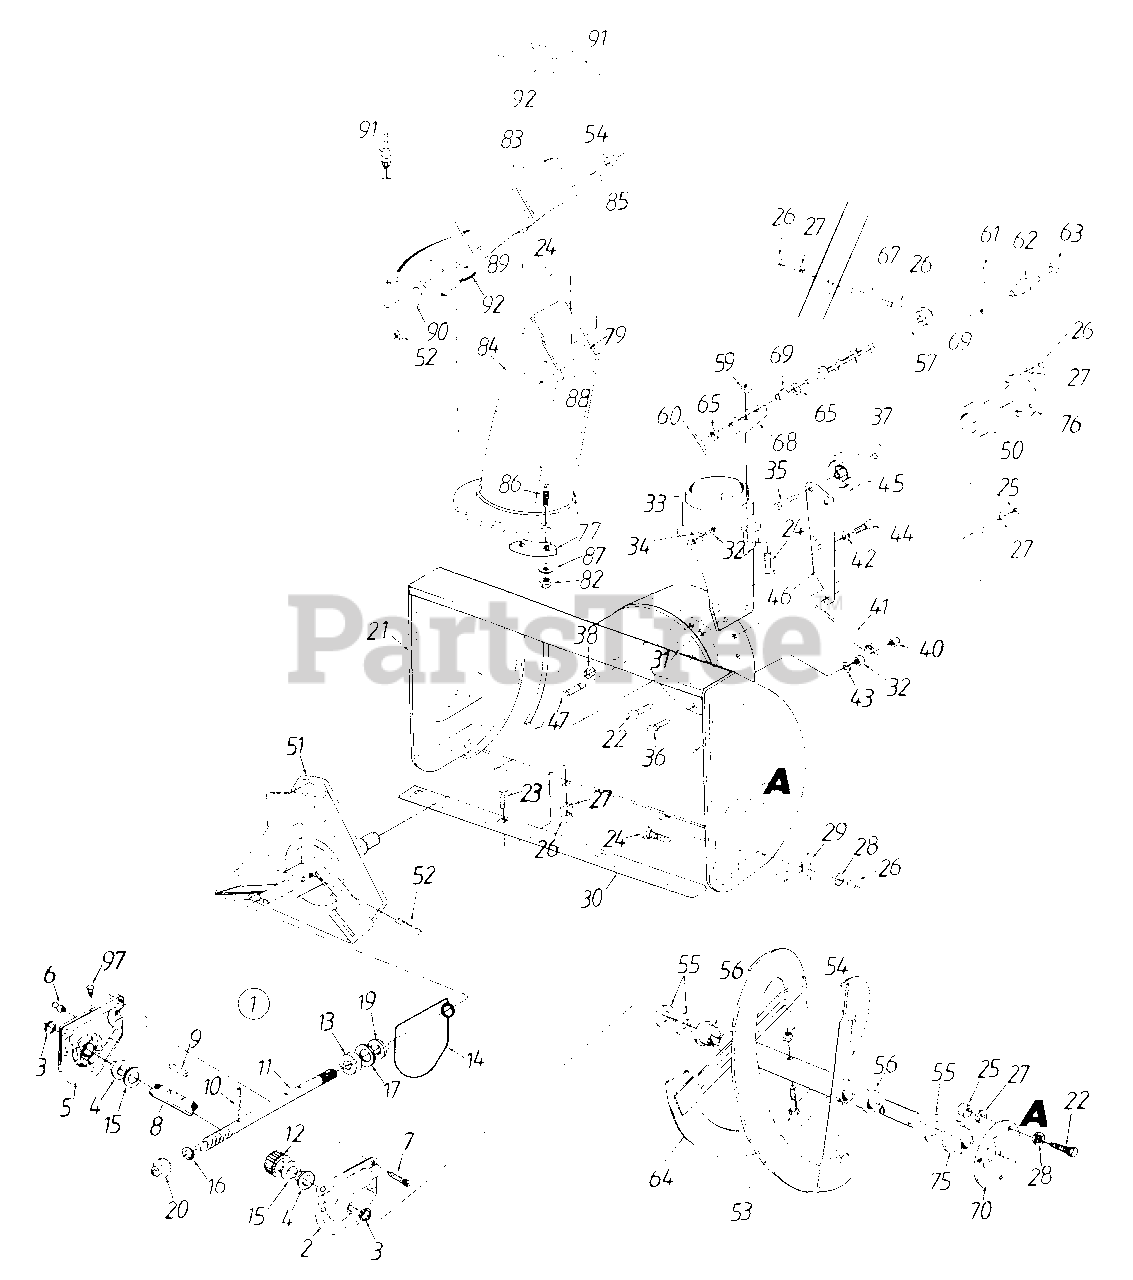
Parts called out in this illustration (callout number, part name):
1	Worm Drive Ass'y. Comp.
2	Reducer Housing - L.H.
3	Oil Seal
4	Flange Bearing .75" I.D.
5	Reducer Housing - R.H.
6	Grease Fltting
7	Hex TT-Tap Scr. 1/4-20 x .75" Lg.
8	24" Auger Shaft
9	#61 Hi-Pro Key 3/16" x 5/8" Dia.
10	Spiral Pin 1.25" Lg.
11	Impeller Shaft
12	Worm Gear
13	Thrust Collar
14	Oil Seal
15	Fl-Wash .76" I.D. x 1.5" O.D.
16	Fl-Wash .5" I.D. x 1" O.D.
17	Fl-Wash .76" I.D. x 1.49" O.D.
19	Flange Bearing .75" I.D.
20	Flange Bearing .503" I.D.
21	24" Auger Housing Ass'y.
22	Hex Bolt 5/16-24 x .75" Lg.
23	Carriage Bolt 5/16-18 x .62" Lg.
24	Carriage Bolt 5/16-18 x .75" Lg.
25	Hex Nut 5/16-24 Thd.
26	Hex Nut 5/16-18 Thd.
27	L-Wash. 5/16" I.D.
28	Bell-Wash .345" I.D. x .88" O,D.
30	24" Shave Plate
31	Truss Mach. Scr. 1/4-20 x .5" Lg.
32	Hex Nut 1/4-20 Thd.
33	Chute Adapter
34	Spring Washer 1/4" I.D.
35	Hex Bolt 3/8-24 x 1.5" Lg. (Gr. 5)
36	Hex Bolt 1/4-20 x .75" Lg. (Gr. 5)
37	Hex Ins. L-Nut 3/8-24 Thd.
38	Hex Top L-Nut 3/8-16 Thd.
40	Hex L-Nut 1/4-20 Thd.
41	Ext. Spring 3.6" Lg.
42	Fl-Wash. 5/8" I.D. x 1.25"
43	L-Wash. 1/4" I.D.
44	Shld. Bolt .625" Dia. x .170" Lg.
45	Fl-Idler 2.75" O.D.
47	Hex Bolt 5/16-18 x 5/8" Lg.
50	Ball Bearing .75" I.D.
52	Spiral Pin 1.5" Lg.
53	Shear Bolt 5/16-18 x 1.5" Lg.
54	Hex Cent. L-Nut 5/16-18 Thd.
55	Fl-Wash .76" I.D. x 1.49"
56	Flange Bushing .8" I.D.
57	Chute Crank Ass'y.
59	Hex Ins. L-Nut 5/16-18 Thd.
60	Cotter Pin 3/32" Dia. x .75"
61	Roll Pin 1/8" Dia. x .63" Lg.
62	Chute Crank Knob
63	Push Nut
65	Fl-Wash .385" I.D. x .62" O.D.
69	Plastic Bushing .38" I.D.
75	Plastic Bearing w/Flats
76	Bearing Housing
77	Chute Flange Keeper
79	Carriage Bolt 5/16-18 x 1.5" Lg.
82	Hex L-Nut 1/4-20 Thd.
83	Upper Chute
84	Lower Chute
85	Fl-Wash .344" I.D. x 1.125"
86	Truss Mach. Scr. 1/4-20 x .75" Lg.
87	Fl-Wash. 1/4" I.D.
88	Hex AB-Tap Scr. 1/4 x 62" Lg.
89	Cable Guide
91	Chute Control Cable
92	Chute Control Cable w/Clip
